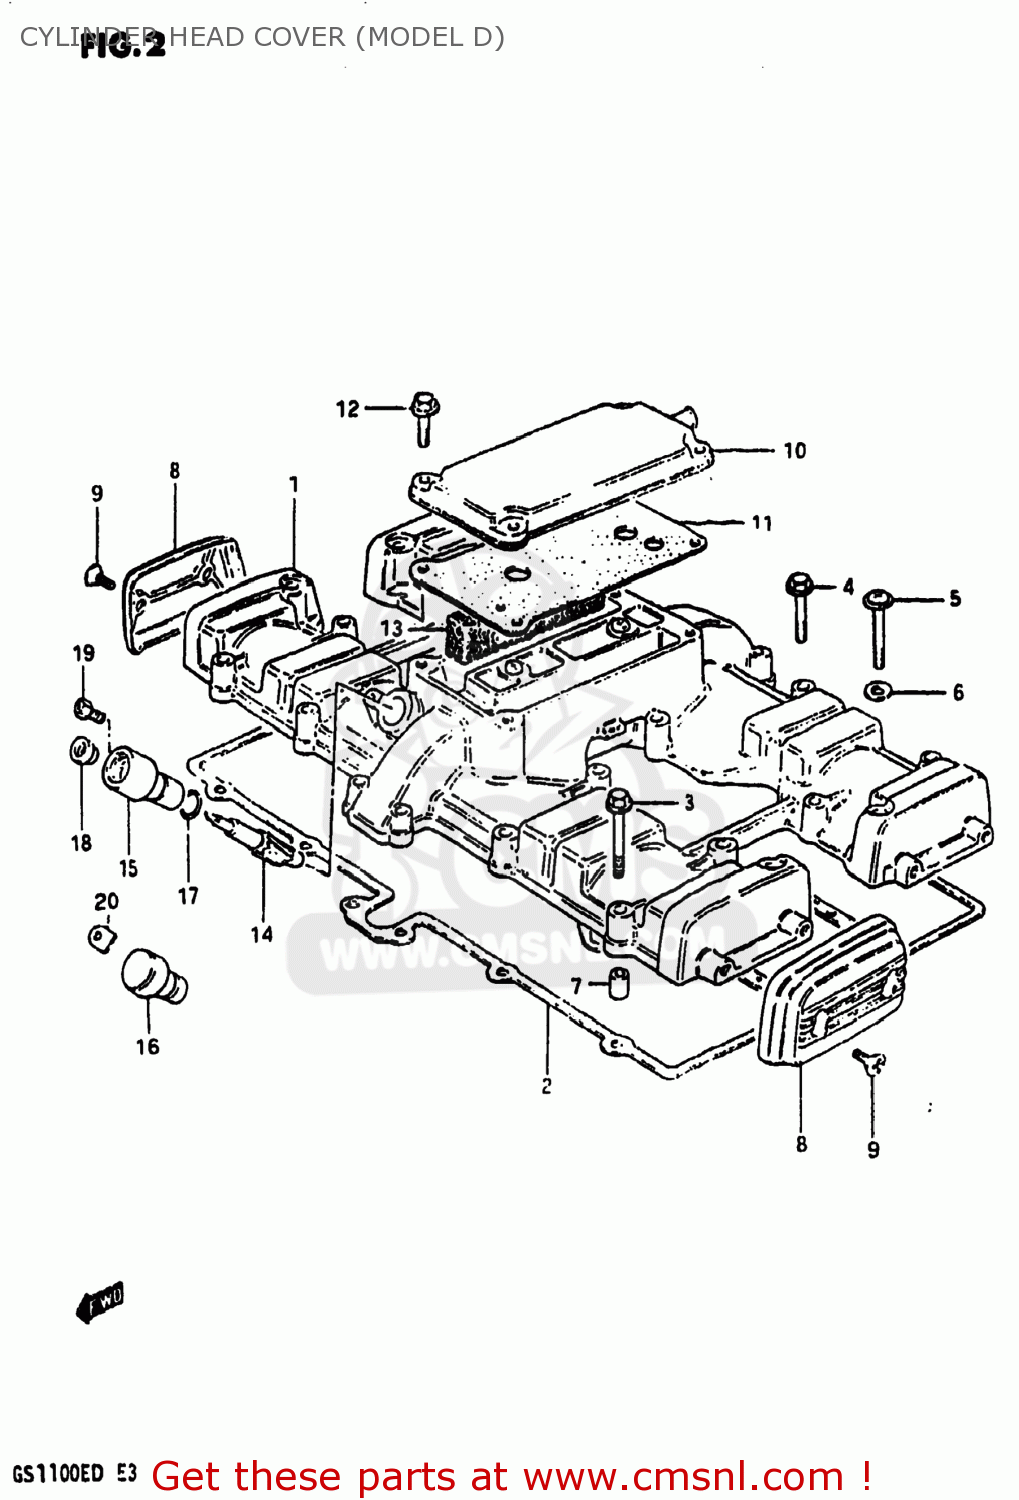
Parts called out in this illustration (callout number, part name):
1	COVER,CYLINDER HEAD
2	GASKET,CYLINDER HEAD COVER
3	BOLT (6X40)
4	BOLT
5	SCREW 6X40
6	GASKET (NAS)
7	PIN(6.2X8X11)
8	CAP,CYLINDER HEAD COVER
9	SCREW(5X12)
10	COVER,BREATHER
11	GASKET (MCA)
12	BOLT
13	COVER,BREATHER
14	GEAR,TACHOMETER DRIVEN
15	SLEEVE,TACHOMETER DRIVE GEAR
16	PLUG,TACH GEAR SLEEVE HOLE
17	SEAL,TACHOMETER DRIVEN
18	SEAL,OIL(5X12X8)
19	SCREW(5X12)
20	PLATE,TACH DRIVE GEAR SLEEVE
